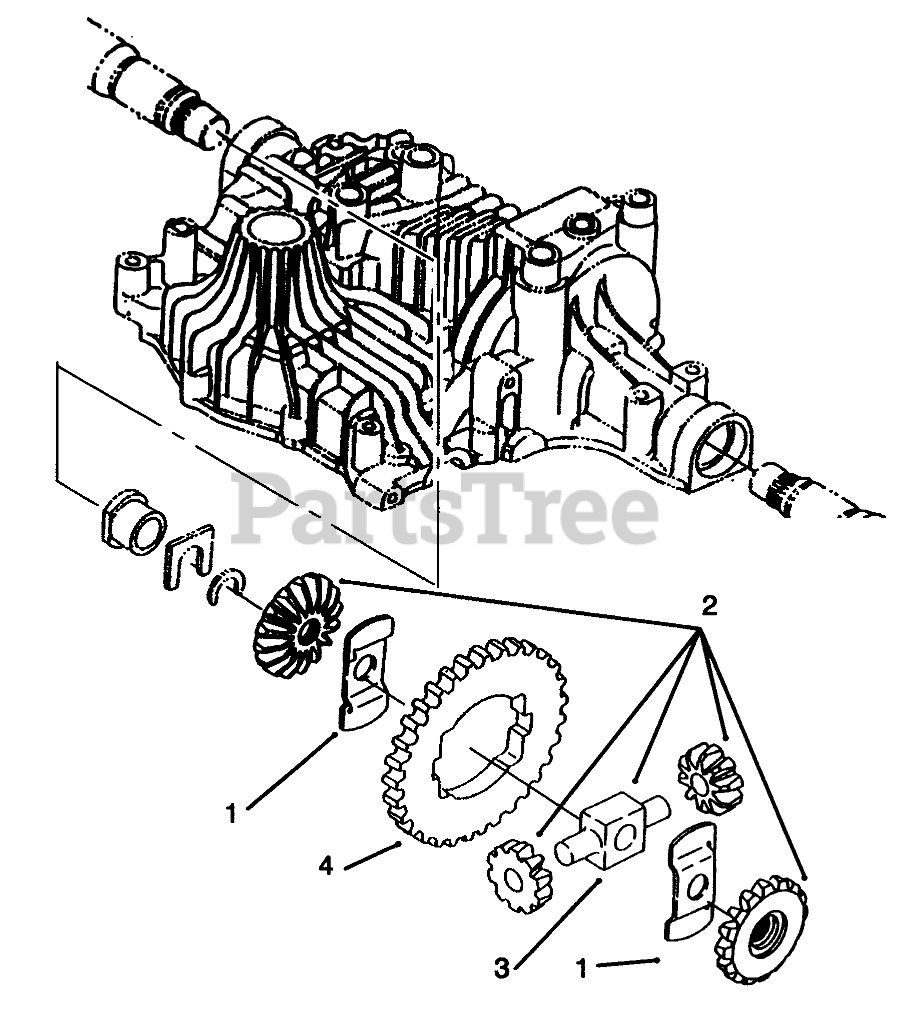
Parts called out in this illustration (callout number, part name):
1	WASHER-THRUST
2	Differential Gear ASM
3	SHAFT - PINION
4	GEAR - FINAL
